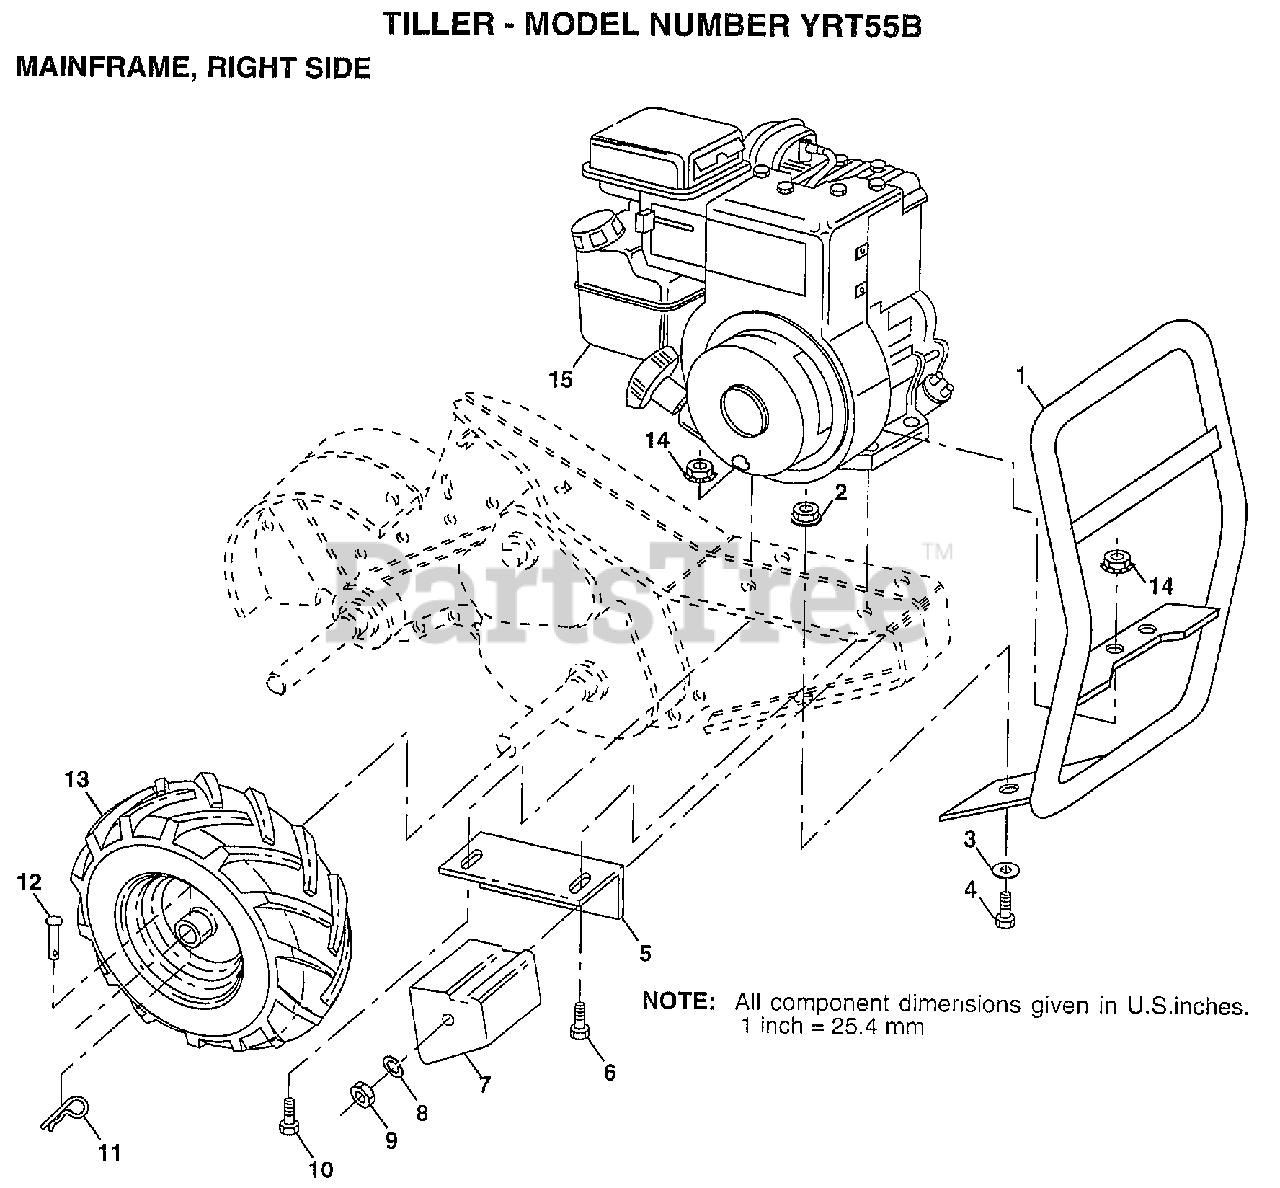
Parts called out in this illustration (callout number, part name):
1	BUMPER
2	LOCKNUT TI
3	WASHER
4	BOLT
5	BRKT REINFORCEMENT
6	BOLT
7	COUNTERWEIGHT CRT
8	LOCKWASHER
9	NUT.HEX.3/8-16UNC
10	BOLT.HEX.5/16-1.5
12	RIVET DRILLED
13	TIRE TI
13	RIM
